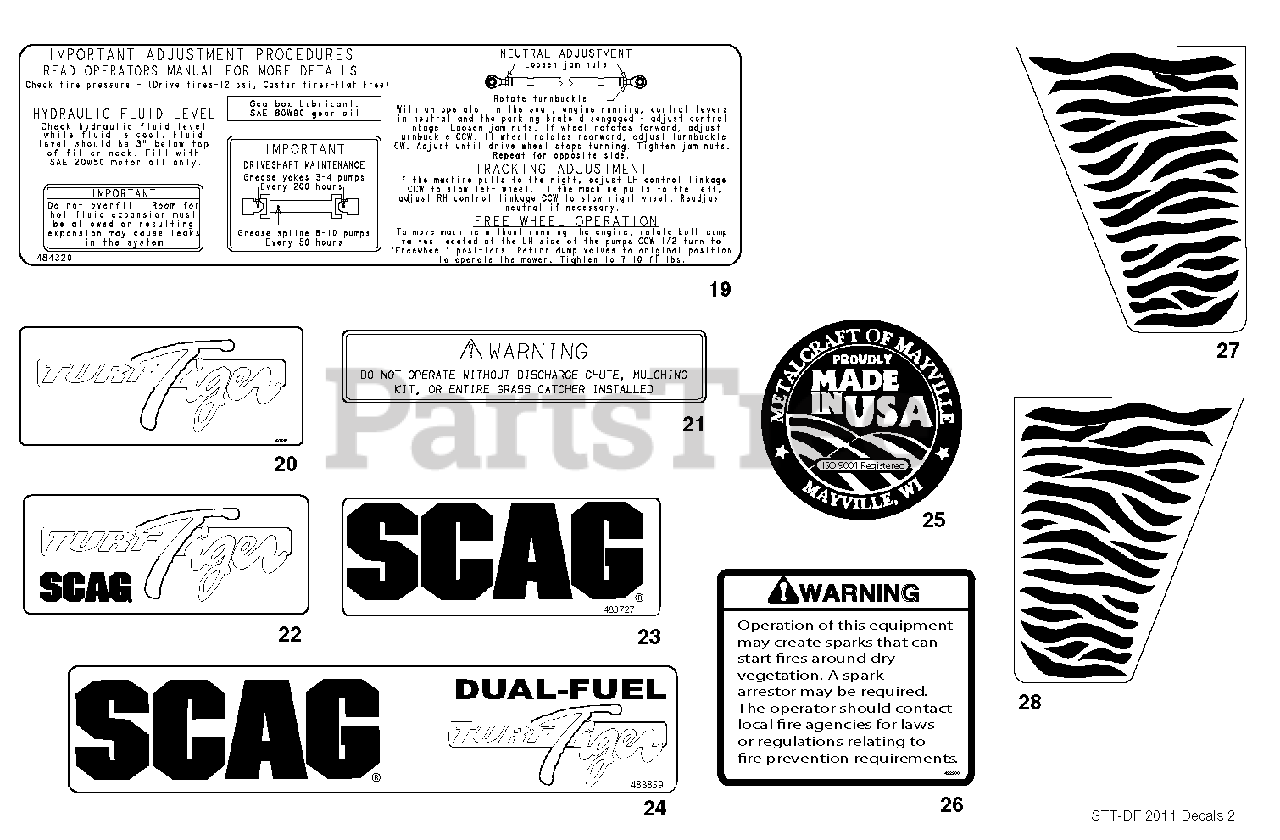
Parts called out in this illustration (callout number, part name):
19	Decal, Checks and Adjustments
20	Decal, Turf Tiger
21	Decal, Warning
22	Decal, Turf Tiger
23	Decal, Scag Logo
24	Decal, Scag Dual-Fuel
25	Decal, Metalcraft-Made In USA
26	Decal, Warning Spark Arrestor
27	Decal, Stripes-RH
28	Decal, Stripes-LH
